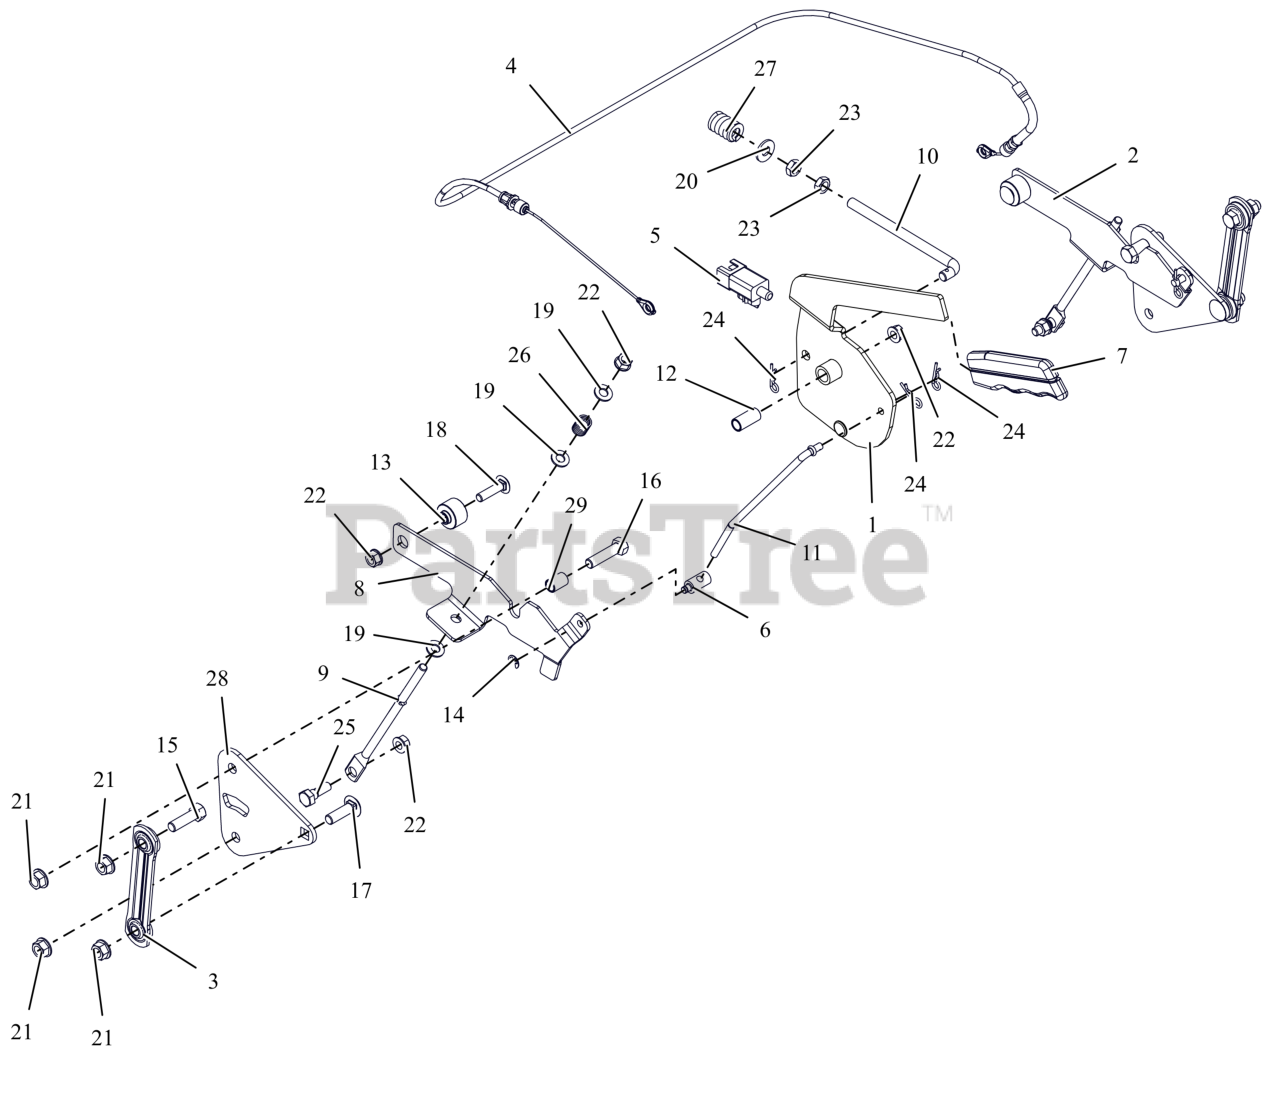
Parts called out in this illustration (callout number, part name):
1	LEVER, PARKING BRAKE
2	ARM, BRAKE - LH (W/PIN)
3	LINK, STAMPED STEERING
4	CABLE, BRAKE - PARKING
5	SWITCH, SNAP IN - N.O./N.O.
6	TRUNION, 1/4-20
7	GRIP, PARKING BRAKE (YELLOW)
8	ARM, BRAKE - RH
9	ROD, LINK - TRANSMISSION BRAKE
10	ROD, OVER CENTER
11	ROD, BRAKE LINK
12	BSHG-SLV .385X.500X1.045
13	SPCR, FLANGE
14	RG-RTNG-EXT .250X.025
15	BLT, HEX .38-16X1.25 G5 ZCC
16	BLT, HEX .38-16X1.50 G5 ZCC
17	BLT,RHSSN .38-16X1.25 G5 ZCC
18	BLT, RHSSN.31-18X1.25 G5 ZCC
19	WSHR,FLT .344X.688X.065 ZCC
20	WSHR,FLT .375X.875X.083 ZCC
21	NUT-LK-TOP-FLG .38-16 ZC120
22	NUT-LK-TOP-FLG .312-18 GF ZCC
23	NUT-JAM .375-16 G2 ZCC
24	PIN, HAIR #213 .08X1.19 ZCC
25	BOLT,SHLDR .38X.25 -.31-18X.75
26	SPRING, COMPRESSION
27	SG-COMP .187X.56X1.62
28	PLATE, TRANSAXLE (BLACK)
29	SPCR SLEEVED .385X.500X.718
